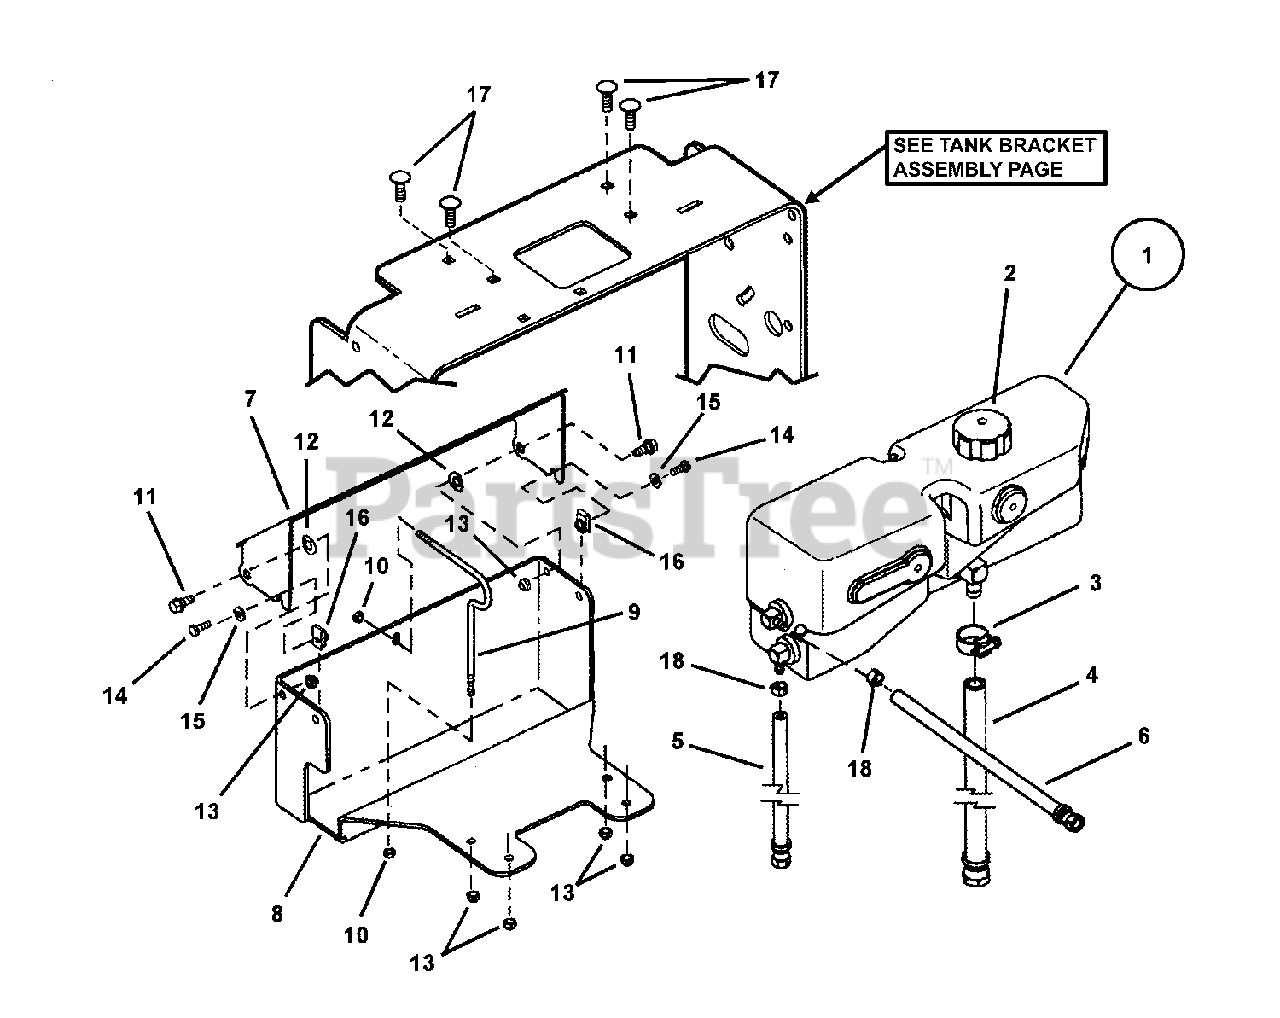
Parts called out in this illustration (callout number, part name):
1	OIL TANK (Includes Item 2)
2	CAP, Oil Tank, Vented
3	CLAMP, 13/16" Hose
4	HOSE, 1/2 x 19-1/2" Supply (3/4-16 Fitting on One End)
5	HOSE, 1/2 x 24-1/2" Return (7/16-20 Fitting on One End)
6	HOSE, Return, 10-1/2" (7/16-20 Fitting on One End)
7	COVER, Oil Tank Bracket
8	BRACKET, Reservoir, Hydro
9	RETAINING ROD, Reservoir (1/4-20 threads)
10	NUT, 1/4-20 Hex Top Lock, GR B
11	SHOULDER BOLT, 5/16-18
12	WASHER, 3/8" Curved
13	NUT, 5/16-18 HEX NYLON LOCK
14	SCREW, 1/4-20 x 3/4" Hex Head Cap, GR 5
15	SHOULDER BOLT, 3/8-16 x 2-7/16"
16	U-NUT 1/4-20
17	BOLT, 5/16-18 x 1" Short Neck Carriage, GR 5
18	CLAMP, Fuel Hose
